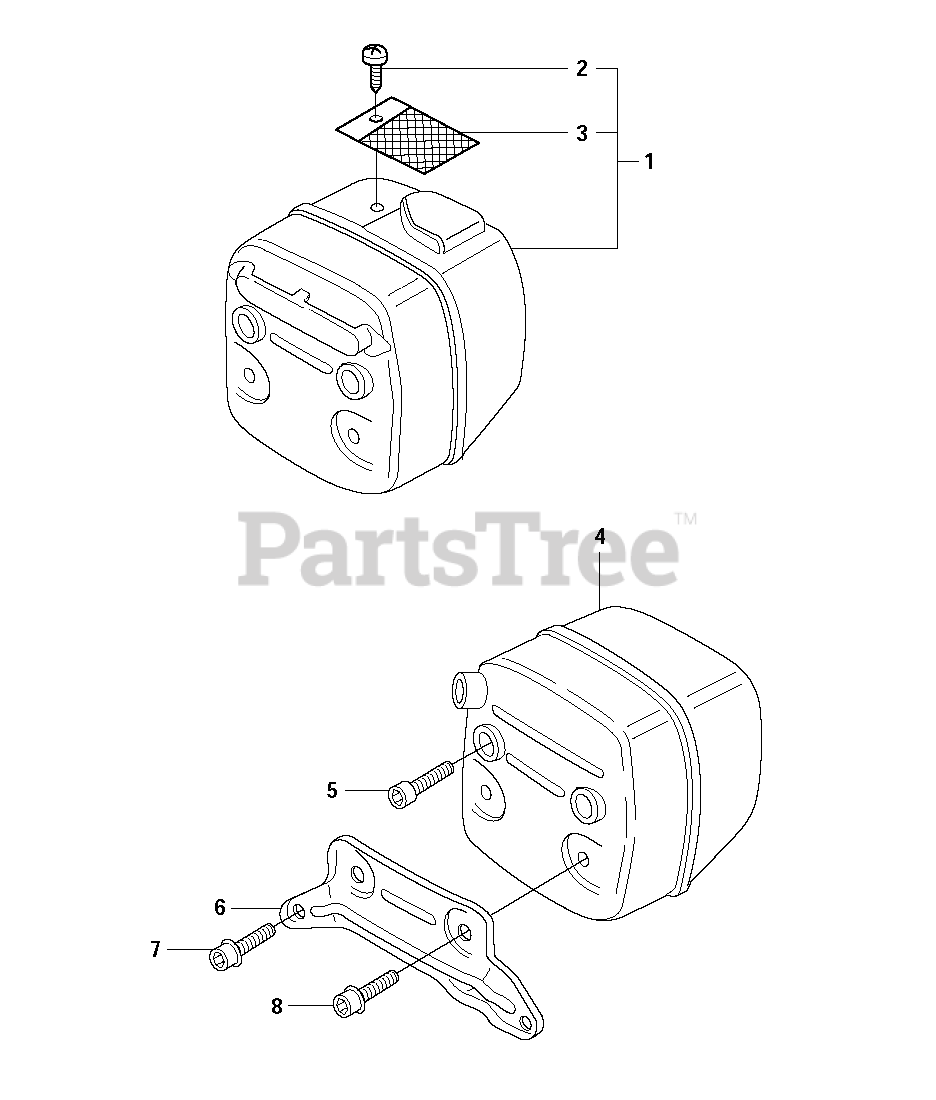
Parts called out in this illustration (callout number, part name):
1	MUFFLER
2	SCREW
3	SCREEN
4	MUFFLER ASSY
5	SCREW MC6S 6X20
6	SUPPORT
8	RP SCREW
